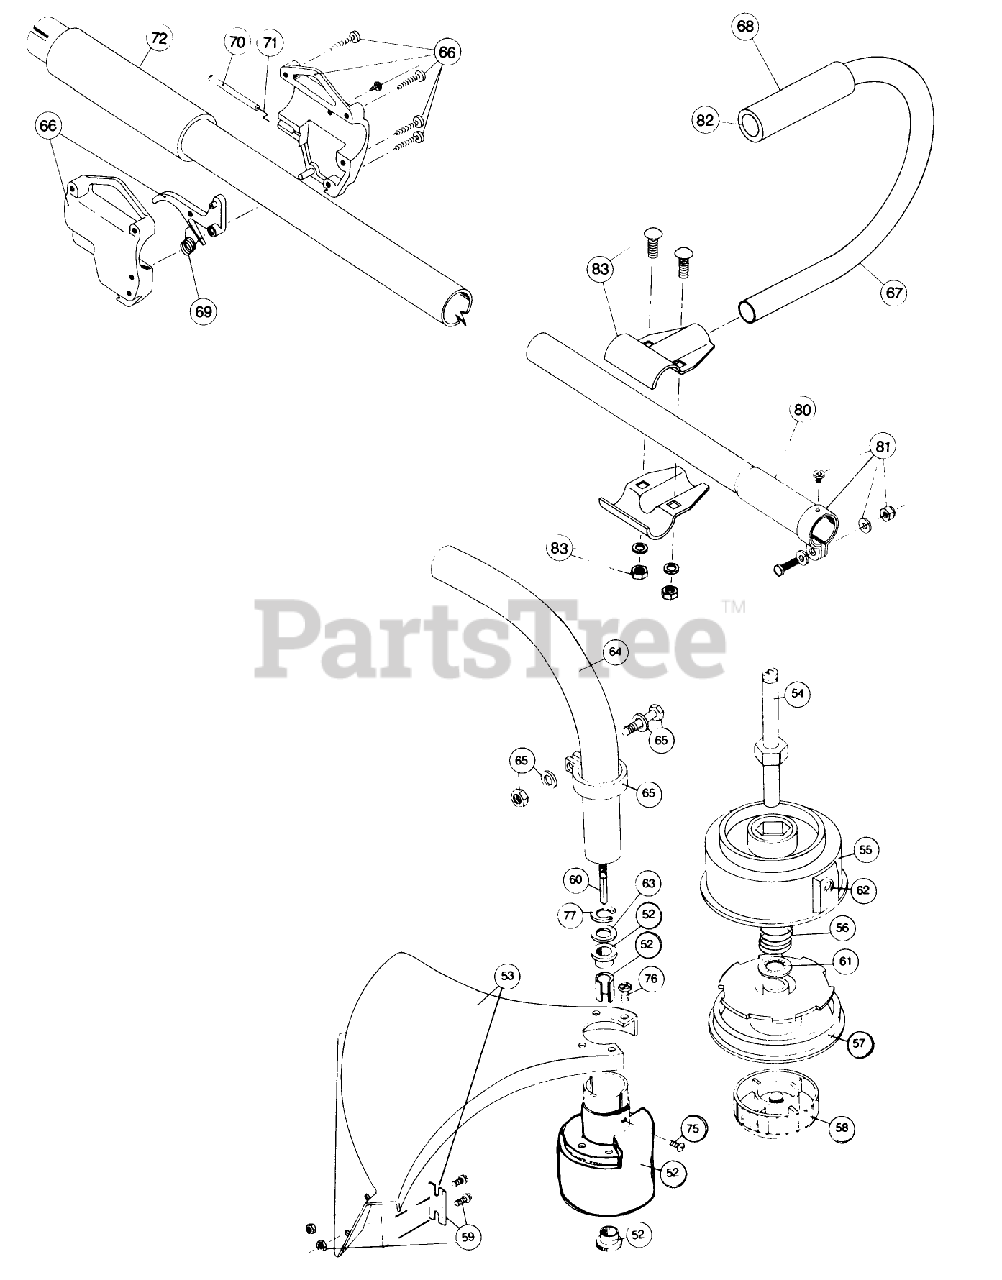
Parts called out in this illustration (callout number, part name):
52	BUSHING HSG ASM
57	REEL - INNER
59	BLADE ASM
61	RETAINER WASHER
66	THROTTLE TRIGGER ASM
68	HANDLE NITRILE GRIP
69	THROTTLE TRIGGER SPRING
70	THROTTLE CABLE HSG
71	THROTTLE CABLE WIRE
75	ANTI-ROTATION SCREW
76	GUARD MOUNTING SCREW
77	RETAINING RING
82	TUBE CLOSURE
